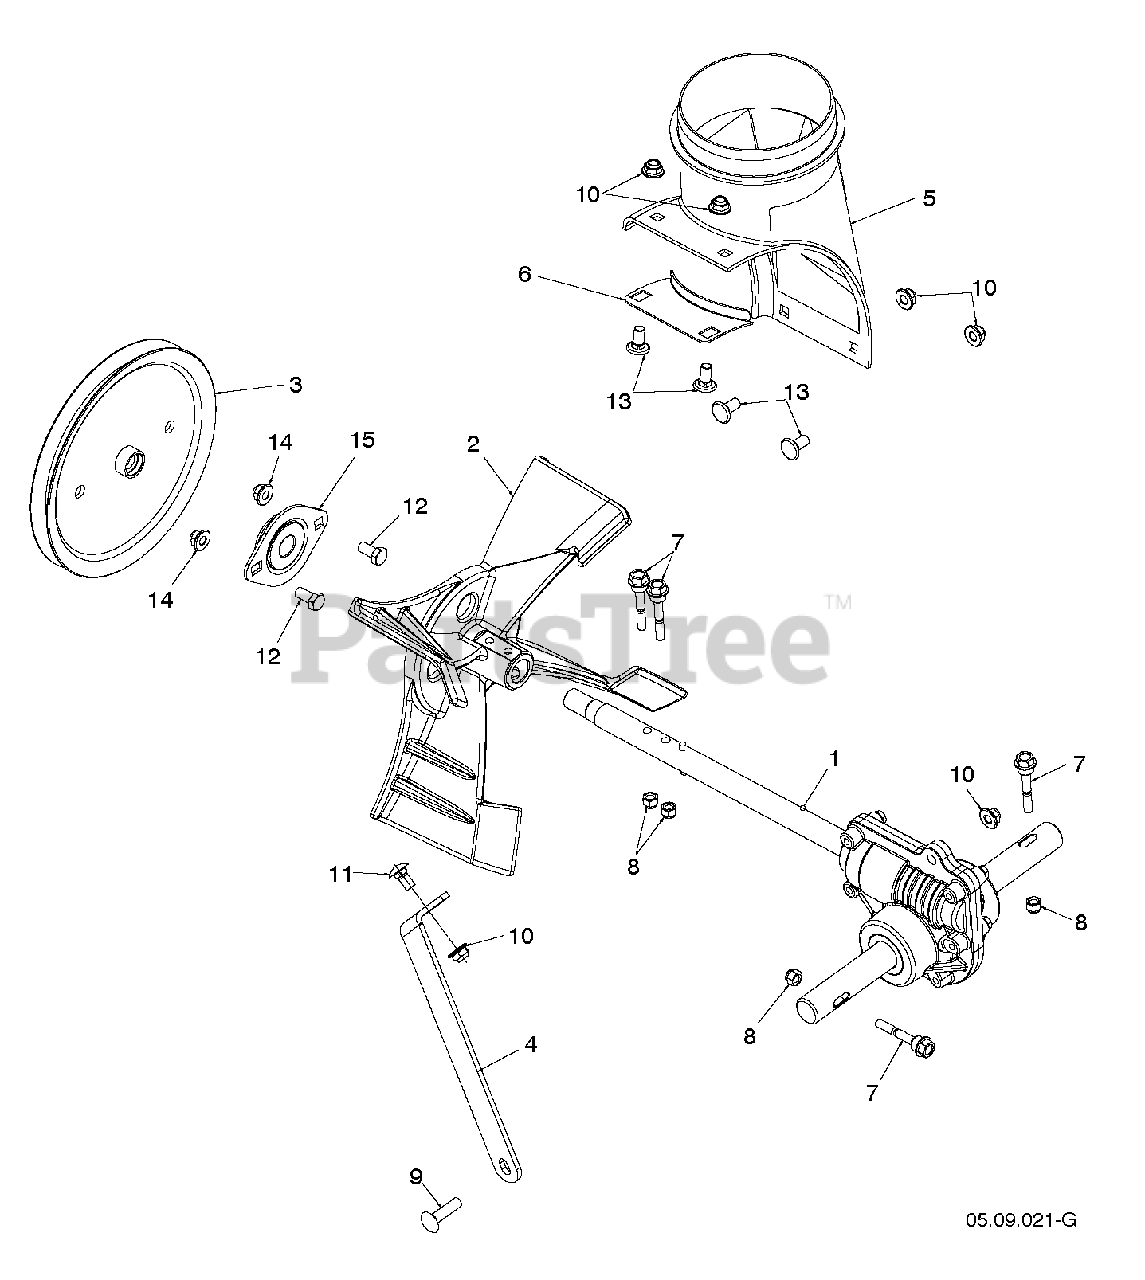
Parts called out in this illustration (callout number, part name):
1	GEAR BOX ASM CAST
2	IMPELLER CAST.IRON.12IN MS 417
3	PULLEY SCREW ON 7.9
4	SUPPORT.GEARBOX.LS.498
5	CHUTE.DISCHARGE.BASE
6	BRACKET, CORNER DISCHARGE
7	BOLT.1/4-20 X 1-13/16 SHEAR
8	LOCKNUT.NYLOC.1/4-20
9	BOLT.CARRIAGE.5/16-18
10	NUT HEX FLG NYLOCK BLK 5_16-1
11	BOLT CAR BLK 5/16-18 X 5/8
12	BOLT, HEX HEAD 5/16-18
13	BOLT CARR WAFER BLK 5_16-18 X
14	NUTNYLOK.FLRANGE.5/16-18
15	BEARING FLANGE
